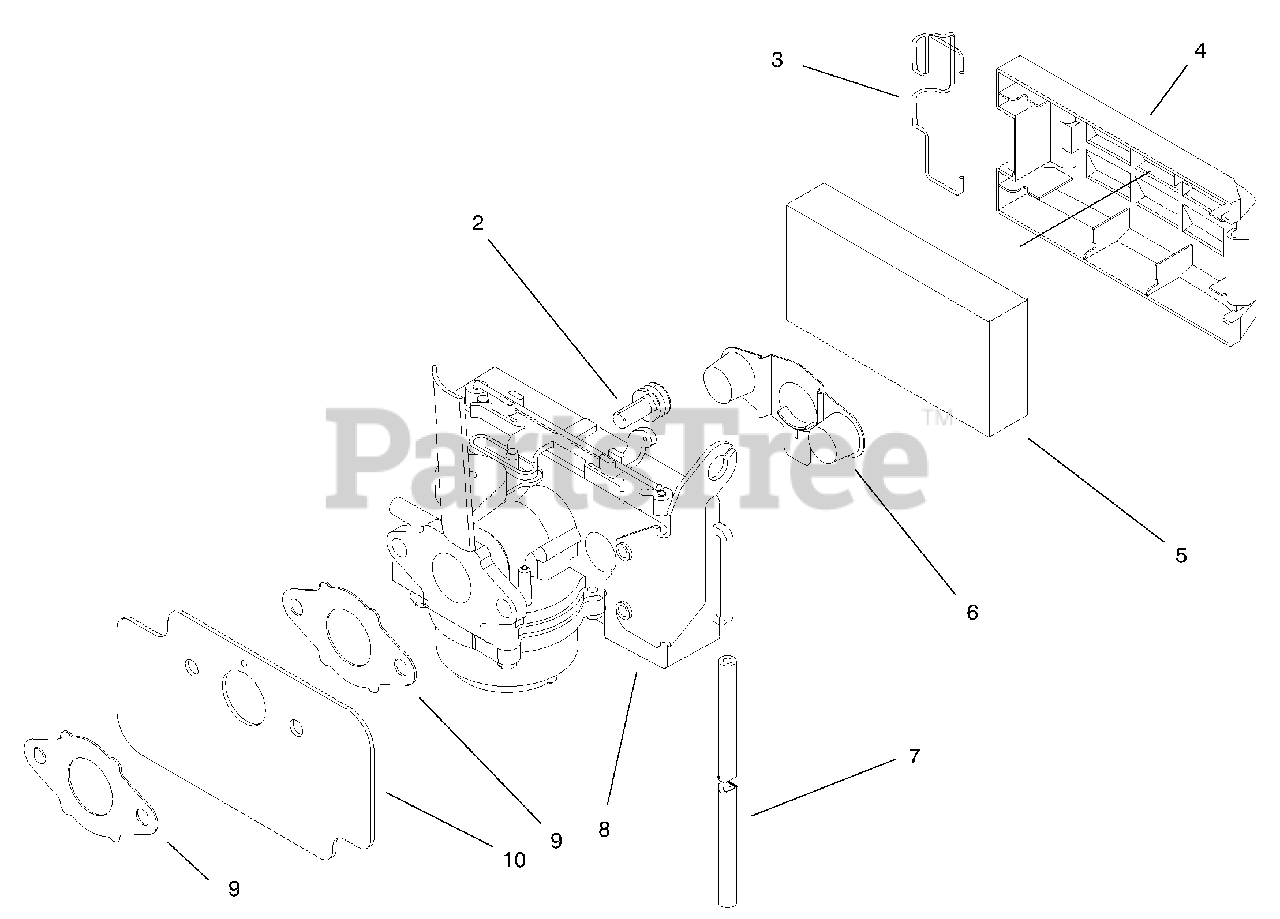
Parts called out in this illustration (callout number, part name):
3	Retainer-Filter
4	Cover-Air Cleaner
5	Element-Filter Air
6	Shield-Fuel
7	Hose-Primer
8	Carburetor Assembly (Incl. Ref. #9)
9	Gasket-Carburetor
10	Shield-Carburetor
